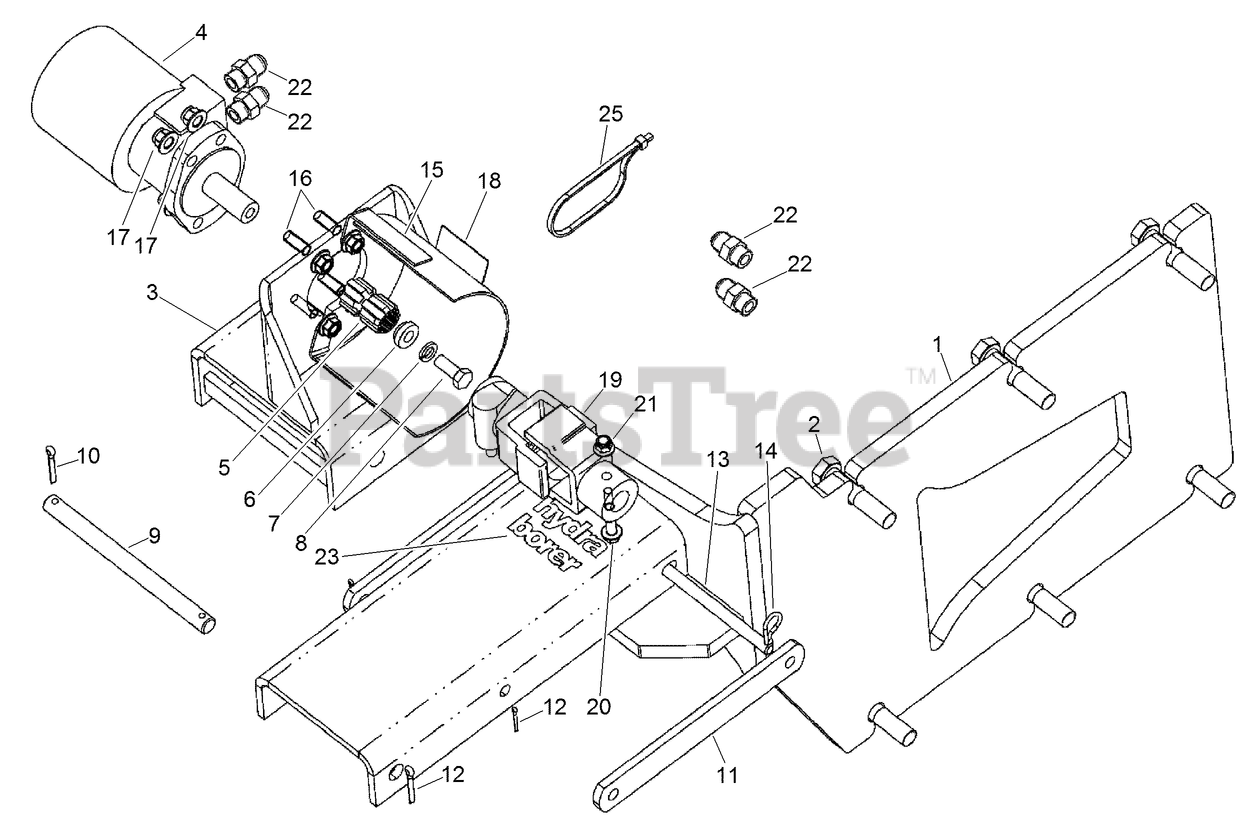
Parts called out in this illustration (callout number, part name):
1	WELDMENT-Frame, Mounting
2	SCREW-HH
3	WELDMENT-Hydra-Borer Mount
4	HYD MOTOR ASM
5	ADAPTER
6	RETAINER-ADAPTER
7	WASHER-Spring Lock Reg 1/2 ZND
8	BOLT-Hex Hd, 0.500 UNF x 1.25 GR5 ZND
9	PIN-Pivot
10	PIN-Cotter, 0.25 x 1.50 in ZN
11	LINK-Hydra-Borer Support
12	PIN-COTTER
13	PIN-Pivot
14	PIN-Hair
15	WELDMENT-Shield, Hydra-Borer Shaft
16	SCREW-HHF
17	NUT-HHF, LOCK
18	DECAL-Entanglement
19	U-JOINT ASM
20	SCREW-HHF
21	NUT-FLANGE, NYLOCK
22	CONNECTOR-Str Thd 5/8, 37FL-ORB 5/8
23	DECAL-Model Name
25	STRAP-TIE
